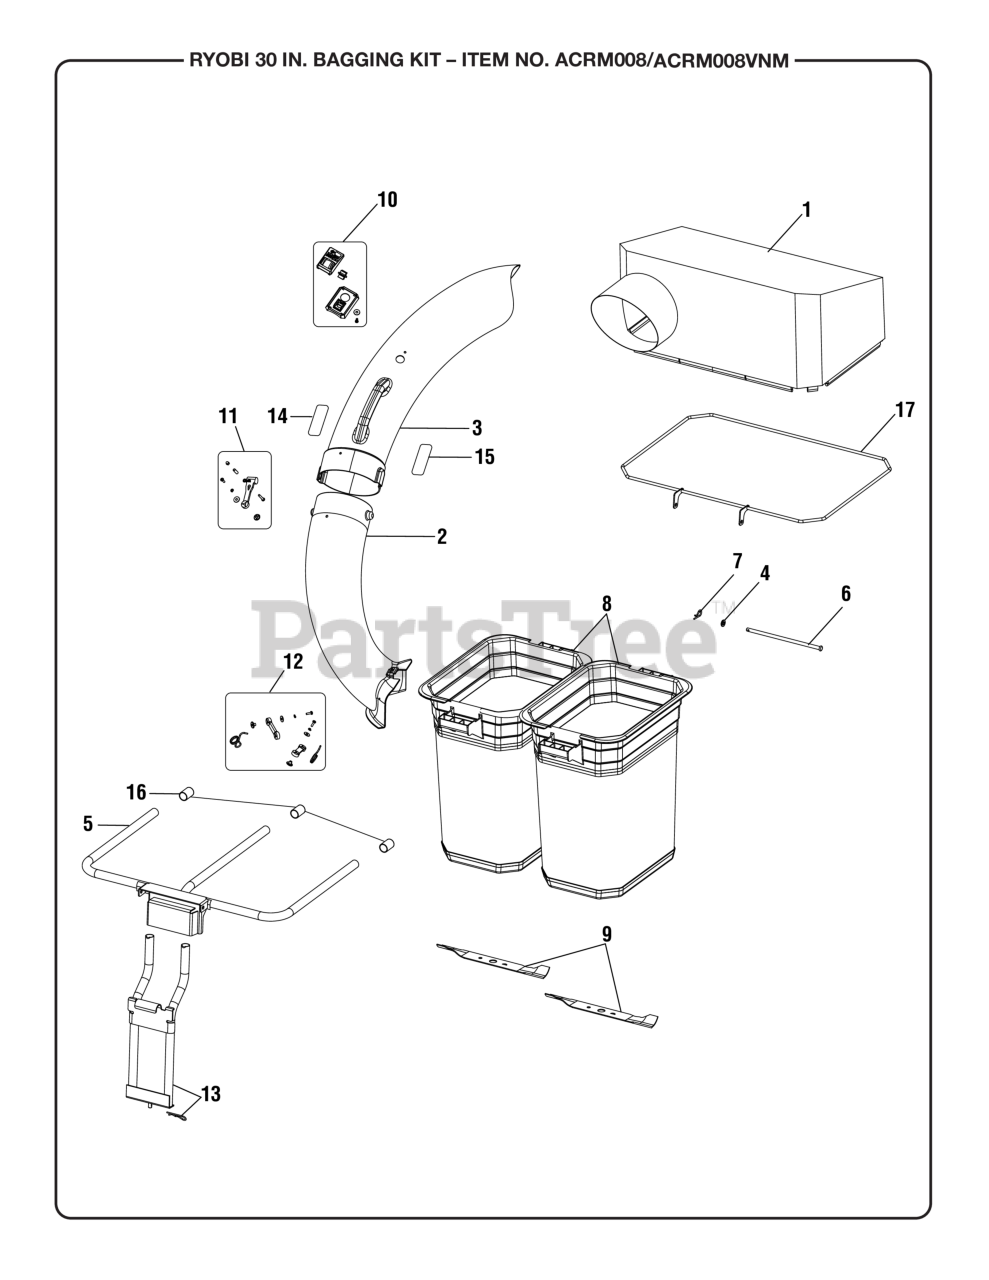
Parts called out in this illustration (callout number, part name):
1	Bagger Cover Assembly
2	Lower Bagger Tube Assembly
3	Upper Bagger Tube Assembly
5	Upper Frame Cover Assembly
6	Hinge Bagger Cover Pin
7	Bagger Hinge Pin Lock
8	Bagger Assembly Bag
9	30 in. Bagging Blade
10	Bagger Gauge Assembly
11	Upper Bungie Tube Connector Kit
12	Lower Bungie Tube Connector Kit
13	Bagger Assembly Lower Frame
14	Bagger Warning Label
15	Bagger Icon Warning Label
16	Hanger Cap
17	Bagger Cover Frame
